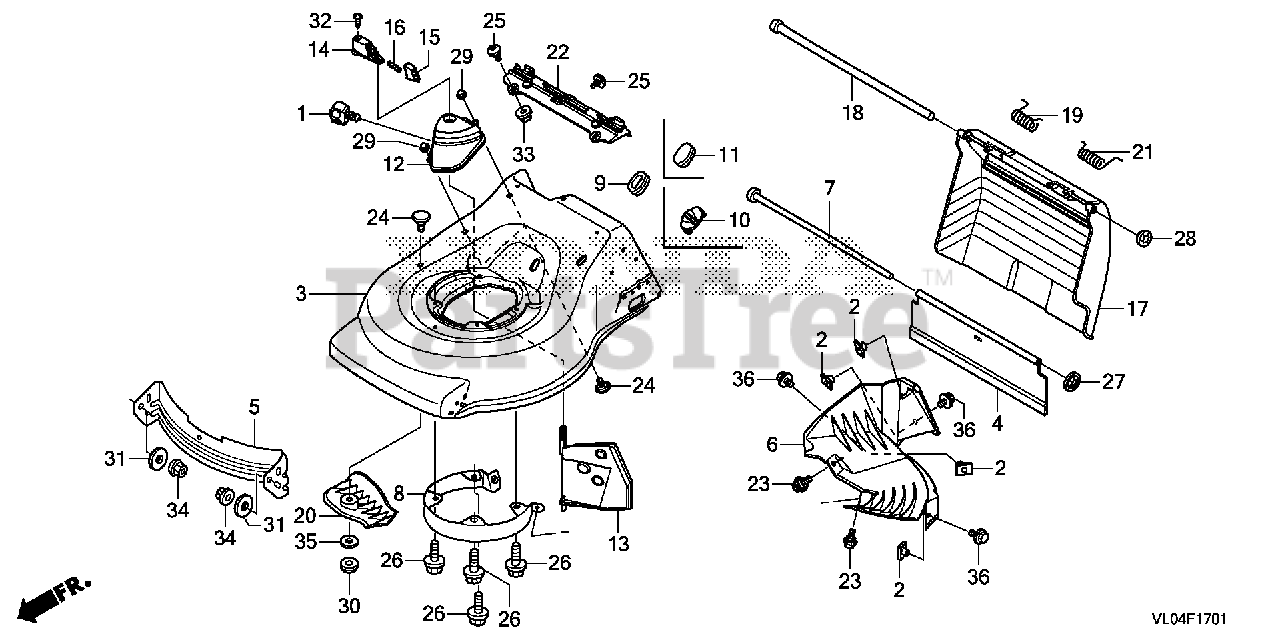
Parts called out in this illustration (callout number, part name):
2	NUT, SPECIAL (6X7)
3	HOUSING, CUTTER *NHB37M* (ROSE CHAMPAGNE LIGHT METALLIC)
4	SHIELD, RR.
5	SCROLL, FR.
6	SCROLL, RR.
7	SHAFT, RR. SHIELD (405MM)
8	COVER, ROTO-STOP
9	GROMMET, CABLE (HOLE)
11	GROMMET, PLUG
12	COVER, SHUTTER
14	LEVER, SHUTTER
15	LOCK, LEVER
16	SPRING, LEVER
17	GUARD, DISCHARGE *NH105* (MAT BLACK)
18	SHAFT, DISCHARGE GUARD
19	SPRING, R. GUARD RETURN
20	RAMP, SCROLL
21	SPRING, L. GUARD RETURN
22	PLATE, GRASS BAG
23	BOLT, SCROLL
24	BOLT, SPECIAL (6X12.5)
25	BOLT, GRASS BAG PLATE
26	BOLT, FLANGE (5/16-24X1")
27	NUT, PUSH (3.96MM) (FLAT ROUND TYPE)
28	NUT, PUSH (7.94MM)
29	NUT, FLANGE CAP (6MM)
30	NUT, NYLON LOCK (6MM)
31	WASHER, PLAIN (5/16)
32	SCREW, TAPPING (5X16) (P0)
33	NUT, FLANGE (6MM)
34	NUT, FLANGE (8MM)
35	WASHER, PLAIN (6MM)
36	BOLT, FLANGE (6X10)
